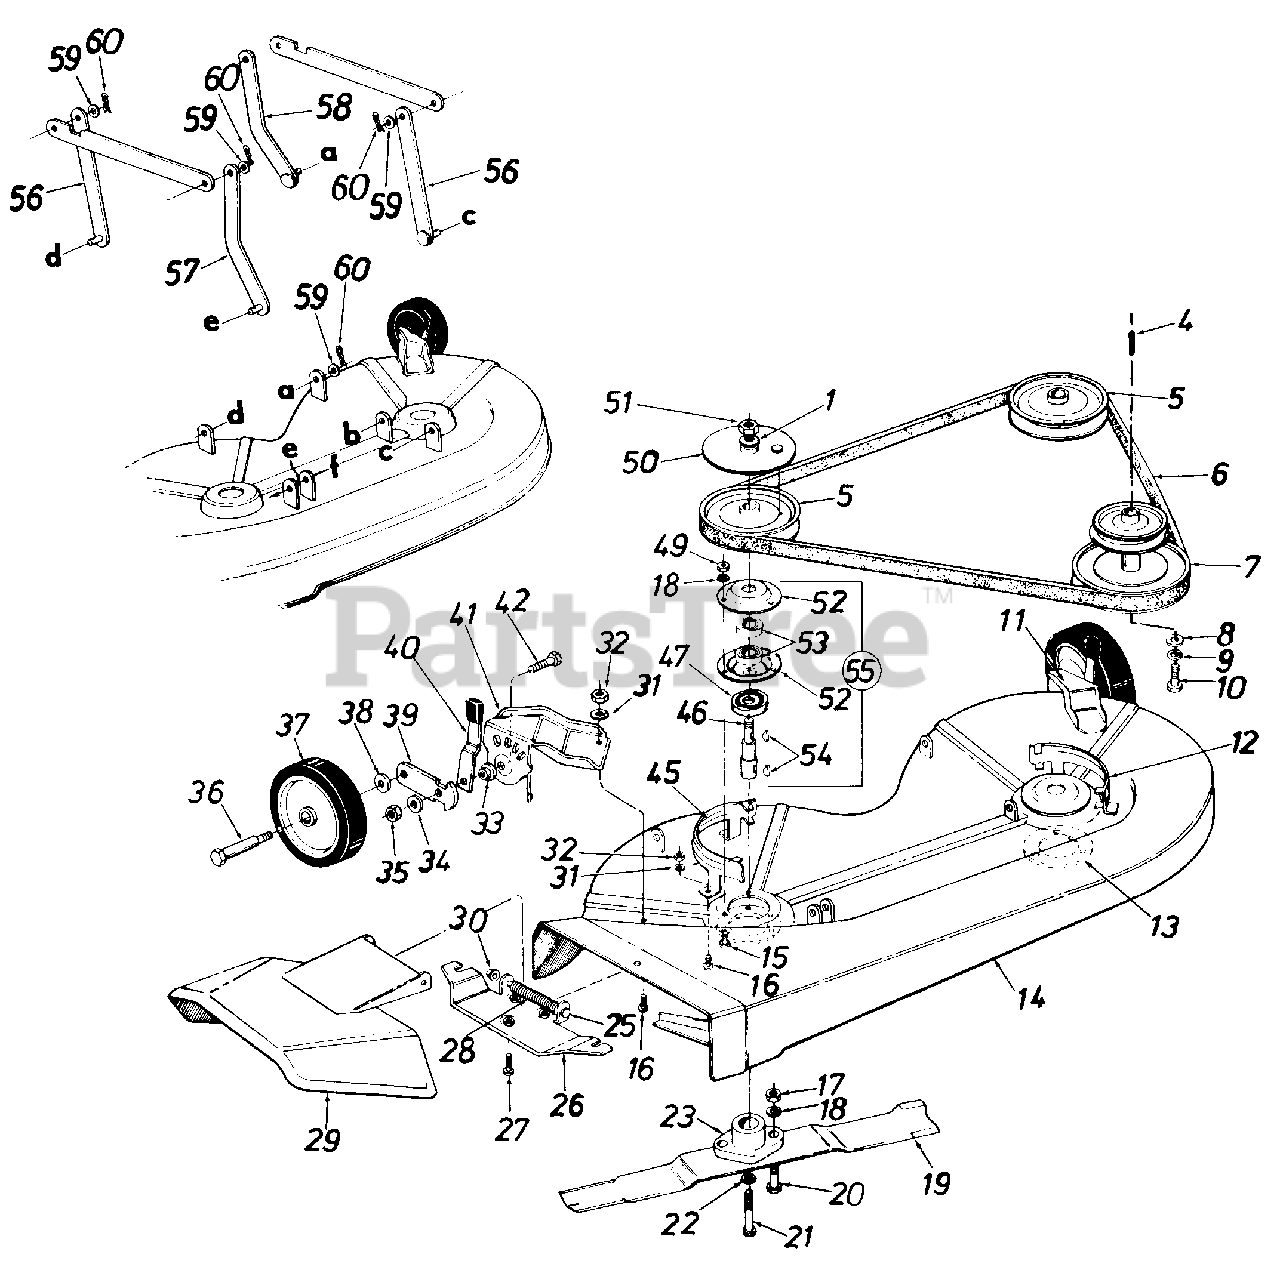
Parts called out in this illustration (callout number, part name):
1	L-Wash. 5/8" I.D.
4	Sq. Key 1/4" x 1/4" x 2.0" Lg.
5	Pulley 4.75" O.D.
6	"V"-Belt 21/32 x 67" Lg.
7	See Lawn Tractor Manual
8	Fl-Wash. 7/16" I.D. x 1.25 O.D. x .180
9	L-Wash. 7/16" I.D.
10	Hex Bolt 7/16-20 x 1.50" Lg.
11	Wheel Brkt. L.H.
12	Belt Guard L.H.
13	Plate Deck Reinforcement
14	34" Deck Ass'y.
15	Hex Sems Bolt 5/16-18 x 1.00" Lg.
16	Hex Bolt 1/4-28 x .50" Lg.
17	Hex Nut 5/16-24 Thd.
18	L-Wash. 5/16" I.D.
19	17" Blade
20	Hex Bolt 5/16-24 x 1.00" Lg. (Grade 5)
21	Hex Bolt 3/8-24 x 1.50" Lg. (Grade 5)
22	L-Wash. 3/8" I.D. (Heavy Duty)
23	Blade Adapter Kit
26	Adapter Plate
27	Hex Wash. Self-Tap Scr. 1/4-20 x .50" Lg.
28	Torsion Spring
29	Chute Cover Ass'y. Comp.
30	Push Nut 1/4' Rod
31	L-Wash. 1/4" I.D.
32	Hex Nut 1/4-28 Thd.
33	Shld. Spacer
34	Bell-Wash. .400" I.D. x 1.13"
35	Hex Top L-Nut 3/8-16 Thd.
36	Shld. Bolt .498" Dia. x 1.53"
37	Plastic Wheel 5.0" x 1.38"
38	Bell-Wash. .400" I.D. x .88"
40	Spring Lever Ass'y. w/ Knob
41	Wheel Brkt. R.H.
42	Hex Bolt 3/8-16 x 1.00" Lg.
45	Belt Guard R.H.
46	Blade Spindle
47	Bearing Shield
49	Hex Nut 5/16-18 Thd.
50	Brake Disc
51	Hex Jam L-Nut 5/8-11 Thd.
52	Bearing Housing
53	Ball Bearing .787" I.D. x 1.85" O.D.
54	#6 Hi-Pro Key 5132" x 5/8" Dia.
55	Blade Spindle Ass'y.
56	Link Deck Hanger Ass'y.
57	Link Deck Hanger Ass'y.
60	Inter. Cotter Pin .50" Dia.
